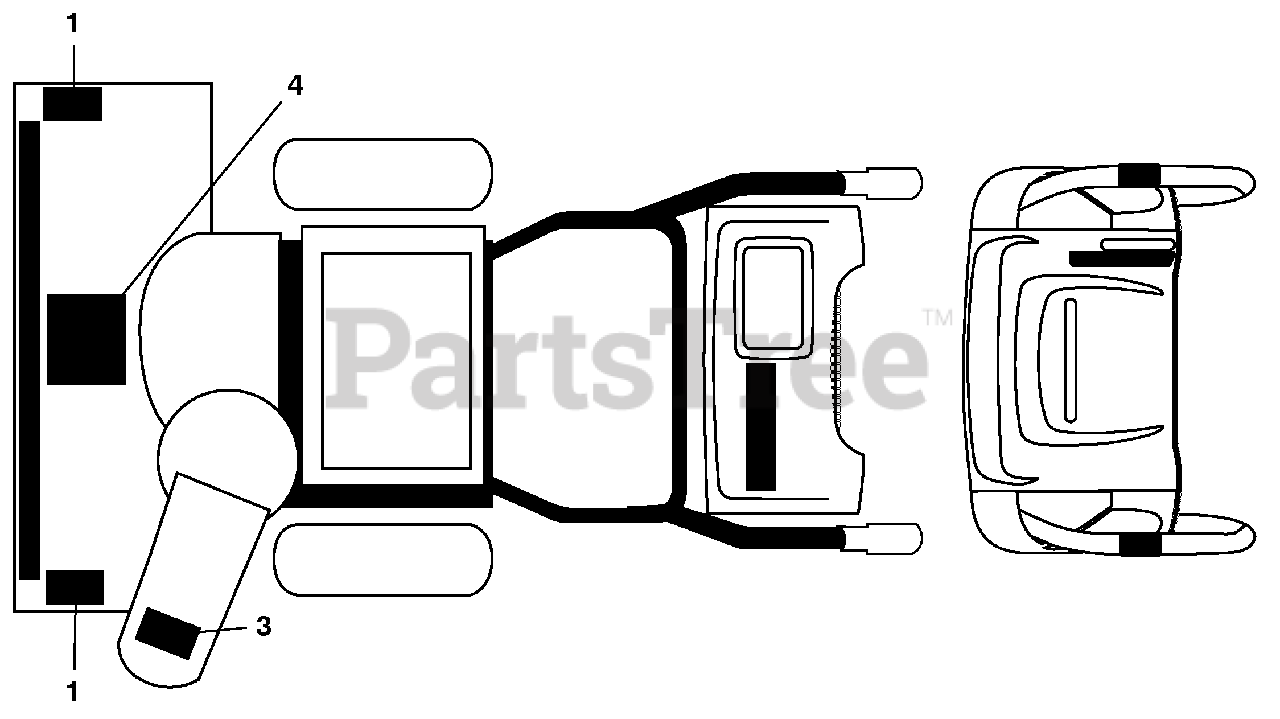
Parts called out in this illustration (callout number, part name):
1	DECAL, DANGER
3	DECAL, DANGER, DEFLECTOR
4	DECAL, DANGER
4	OWNER'S MANUAL, ENGLISH
4	OWNER'S MANUAL, FRENCH
